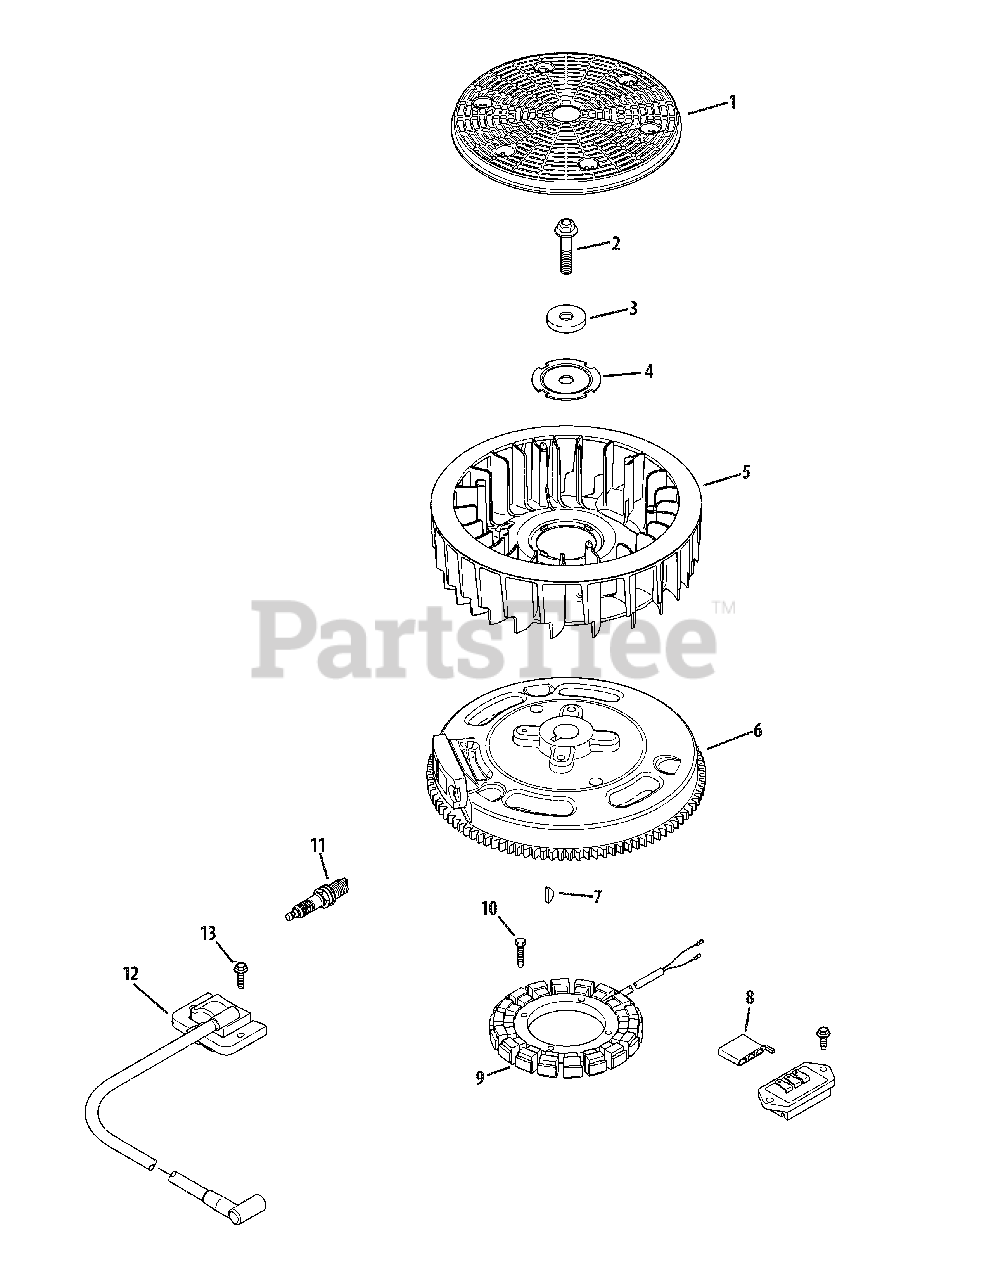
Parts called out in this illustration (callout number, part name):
2	Flange Screw, M10 X 1.5 X 45
3	Flat Washer, 13.32
4	Fan Mounting Plate
5	15 Amp Stator Kit (Inc. KH-25-452-01-S)
6	Flywheel Assembly
7	Key, 3.16 X 5.8
9	15 Amp Stator Kit
10	Screw, M5 X 0.8 X 25
11	Spark Plug
12	Module Ignition Kit
13	Screw, M5 X .8 X 20
